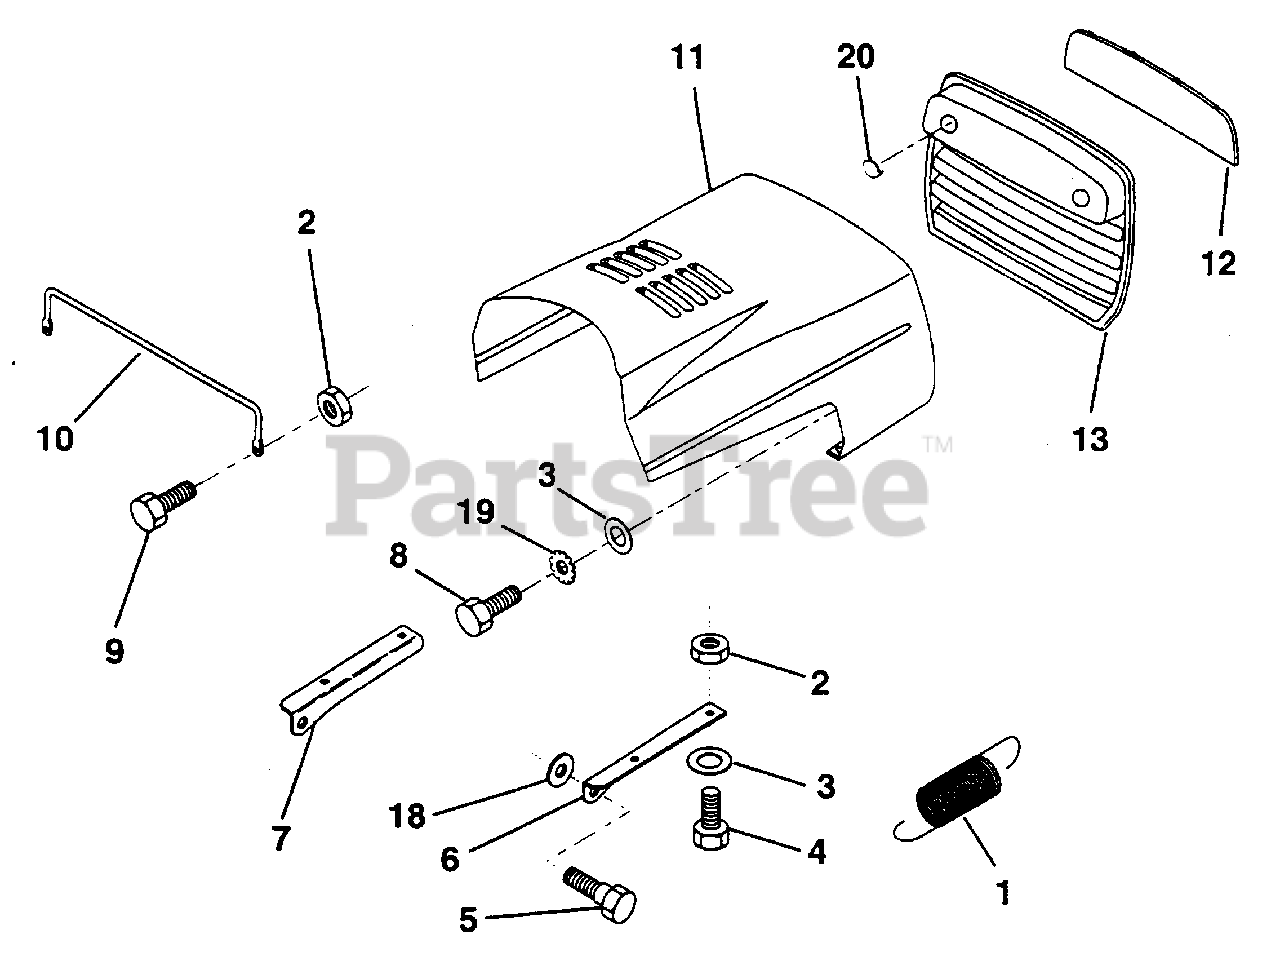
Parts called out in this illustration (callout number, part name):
1	Extension, Spring (AYP part number)
2	Nut, Hex, Keps 1/4-20 (AYP part number)
3	Washer, 9/32 x 5/8 x 16 Ga. (AYP part number)
4	Bolt, Hex Fin. 1/4-20 UNC 5/8 Gr.5 (AYP part number)
5	Bolt, Shoulder (AYP part number)
6	Bracket, Hood R. H. (AYP part number)
7	Bracket, Hood L.H. (AYP part number)
8	Screw, Fin. Hex #13-16 Hi-Lo x 5/8 (AYP part number)
9	Bolt, Hex Fin. 1/4-20 x 3/4 Gr. 5 (AYP part number)
10	Brace, Hood (AYP part number)
11	Hood (AYP part number)
12	Lens, Plate, Grill (AYP part number)
13	Grill (AYP part number)
18	Washer 11/32 x 11/16 x 16 Ga. (AYP part number)
19	Washer Lock 1/4 int/ext tooth (AYP part number)
20	Plug Socket Light
